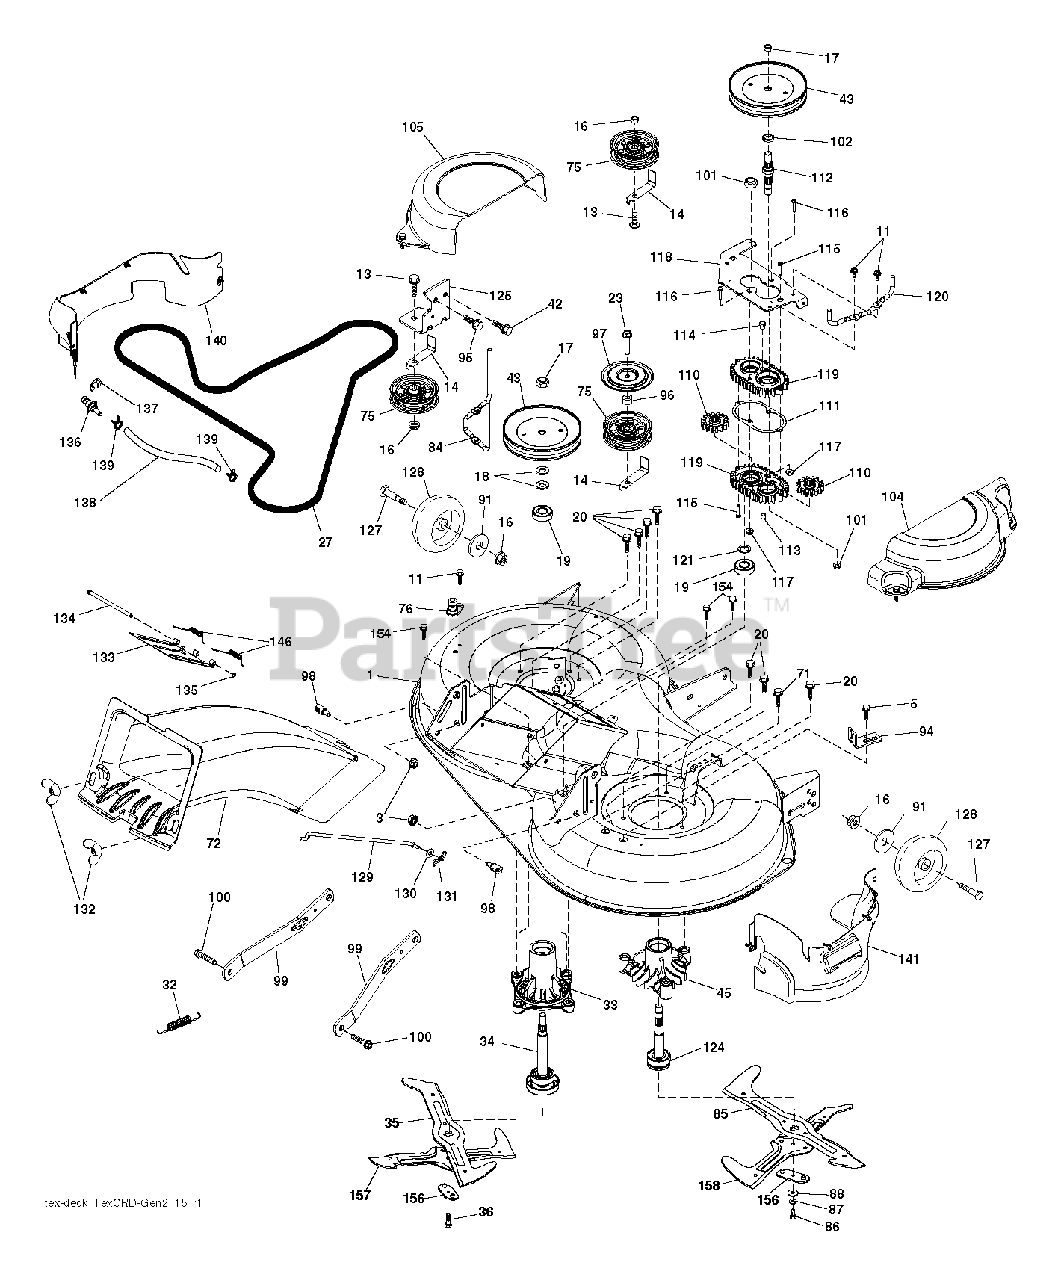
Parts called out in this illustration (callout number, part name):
3	NUT LOCK HEX FLANGE 5/16-18
5	BOLT.5/16HEX.WHS.HD
11	SCREW.1/4-20X5/8
13	BOLT.3/8-16X1.50
14	KEEPER, BELT IDLER
16	NUT LOCK FLG 3/8-16 UNC
17	NUT.FLANGE.LOCK.TOP
18	WASHER.SPACER.MANDREL
20	SCREW, WASHER HEAD
23	SCREW LT
27	BELT BELT. ELECTRIC MOWER DRIV
32	SPRING 107CM & 97CM ELECTRIC D
33	HOUSING.MANDREL.4PT.
34	SHAFT.ASM.MDRL.N/GREASE.38
35	BLADE.3N1.LH.CRD
36	BOLT.WASHER.ASM.7/16-2
42	SCREW
43	PULLEY PULLEY MANDREL 5.438 PD
45	HOUSING.MANDREL.44/46" VENT
71	SCREW 3/8-16X1/2
72	RP 97107.TEX.CRD.UPPE
75	FLAT IDLER PULLEY
76	1/2" BARB.DECK.WASHOUT.PORT
84	KEEPER KEEPER. LH MANDREL BELT
85	BLADE.3N1.RH.CRD
86	BOLT.3/8-24X1.25GR8. LHTHRD
87	LOCKWASHER
88	WASHER.BLADE
91	WASHER
94	BRKT.CLUTCH.CABLE
95	SCREW, 3/8-16X3/4
96	SPACER
97	PROTECTOR
98	STUD.FASTNER.W/ANTI-ROTATE
99	ARM.SUSPENSION.MOWER.R
100	BOLT.SHOULDER
101	NUT.CROWNLOCK.9/16 -18.UNC
102	SPACER BEARING
110	GEAR GEAR OUTPUT
111	GASKET GASKET GEARCASE
112	SHAFT SHAFT. CRD GEARCASE ADAP
113	PLUG PLUG OIL
114	VALVE VALVE RELIEF
115	SCREW
116	BOLT.CARIGE.SS.1/4-20X1.75GR5
117	NUT T
118	ARM ARM. CLUTCHING 107 TEX CRD
119	GEARCASE GEARCASE SUBASM
120	KEEPER KEEPER. RH MANDREL BELT
121	WASHER WASHER
124	MANDREL SHAFT NON/GREASE
125	BRACKET
127	BOLT.SHOULDER.3/8-16X3-5/8.
128	WHEEL. GUAGE RALLY
129	ROD ROD. SWAY CRD GEN II
130	WASHER
131	PIN.COTTER.5/16.BOW TI
132	KNOB.HANDLE.3/8.TRI-POINT.BLAC
133	COVER DOOR.107 CM CRD EZ MULCH
134	PIN PIN.HINGE
135	E-RING.5/16"
136	PLUG WASHOUT PORT HOOKUP
138	107.WASHOUT.PORT.HOSE (2 2)
139	HOSE.3/8.CLAMP (2 2)
140	GUARD FRENCH 107 TEX ASSEMBLY
141	GUARD SUBASM. 107 TEX GEN 2 RH
146	SPRING SPRING: EZ MULCH DOOR
154	SCREW T-30 1/4-20 X
156	ADAPTER ADAPTER.CROSSBLADE.107
157	BLADE 107CM.CROSS.BLADE
158	BLADE.CROSS.RH.CRD.107
